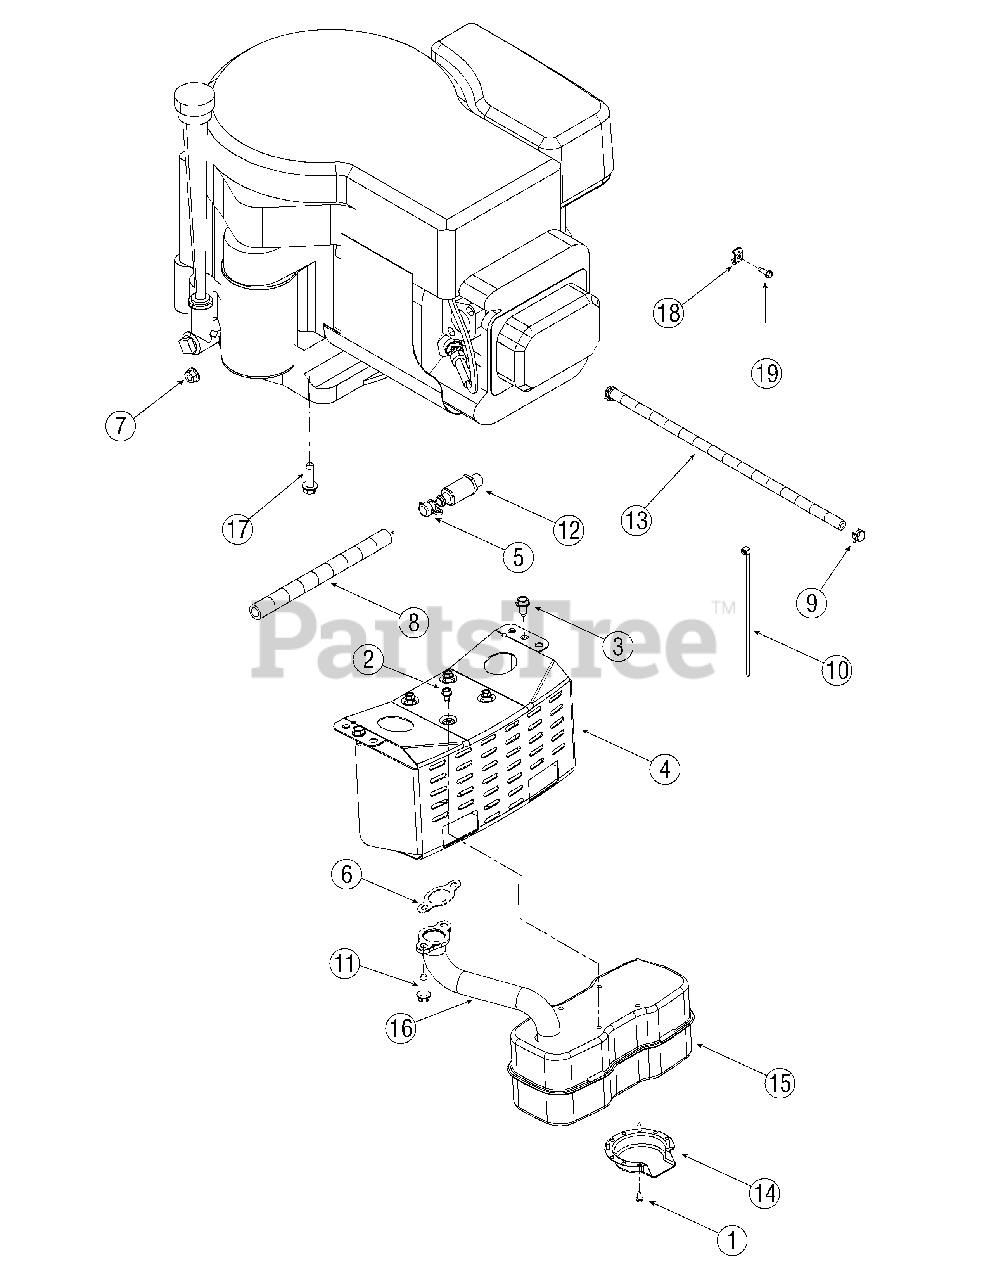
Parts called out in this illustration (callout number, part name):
1	AB Screw #8-18 x 0.5
2	TT Screw 1/4-20 x 0.5
3	AB Screw 5/16-12 x 0.5
5	Oil Drain Cap
6	Exhaust Gasket
7	Sems Nut, 1/4-20
8	OIl Drain Extension Hose
9	Hose Clamp
10	Cable Tie
11	Screw, 5/16-18 x .750
12	Oil Drain Valve
13	Fuel Line Hose
14	Muffler Deflector
15	Single Inlet Muffler
16	Exhaust Pipe
17	Screw, 3/8-16 x 1.250
19	Screw, #10-32 x .625
